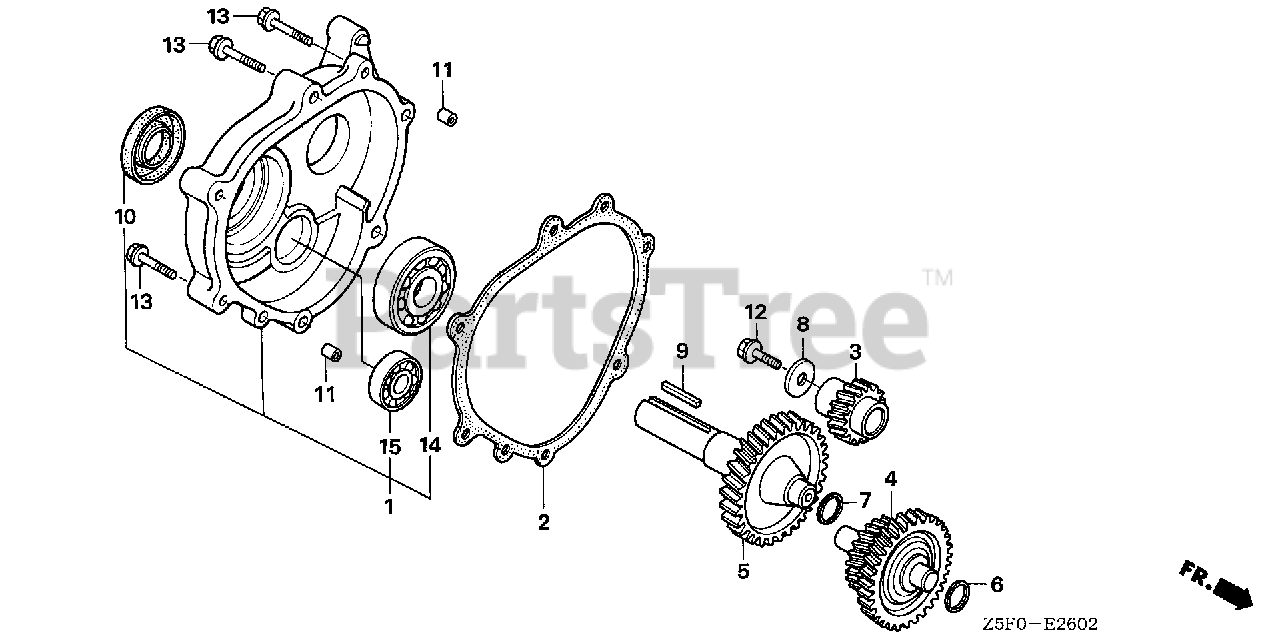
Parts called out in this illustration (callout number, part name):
1	COVER ASSY., REDUCTION CASE
2	GASKET, CHAIN CASE COVER
3	GEAR, PRIMARY DRIVE (17T)
4	COUNTERSHAFT (18T/40T)
5	SHAFT, P.T.O. (46T)
6	SHIM A
7	SHIM B
8	WASHER (8MM)
9	KEY (6.3X6.3X43)
10	OIL SEAL (30X46X8)
11	PIN, DOWEL (8X14)
12	BOLT, FLANGE (8X25)
13	BOLT, FLANGE (8X40)
14	BEARING, RADIAL BALL (6206)
15	BEARING, RADIAL BALL (6302)
